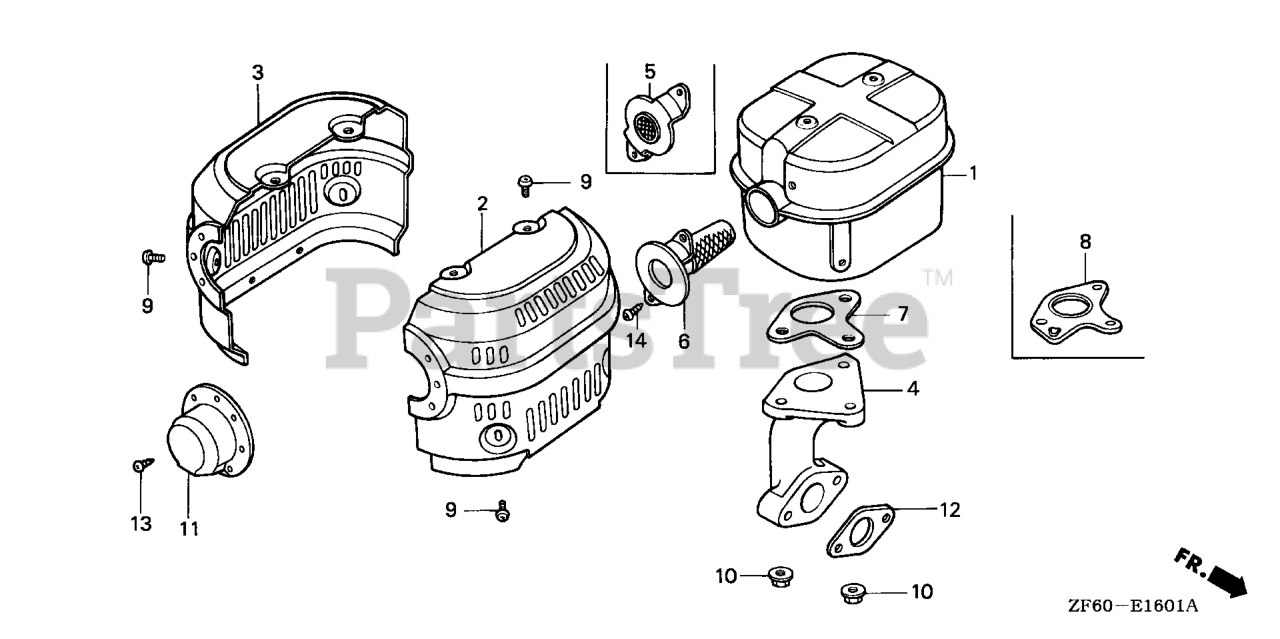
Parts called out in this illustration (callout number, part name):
1	MUFFLER
2	PROTECTOR, R. MUFFLER
3	PROTECTOR, L. MUFFLER
4	PIPE, EX.
5	FLANGE, BAFFLE
7	GASKET, MUFFLER
7	GASKET, MUFFLER (NIPPON LEAKLESS)
9	SCREW, TAPPING (5X8)
10	NUT, FLANGE (8MM)
12	GASKET, EX. PIPE
14	SCREW, TAPPING (5X8)
